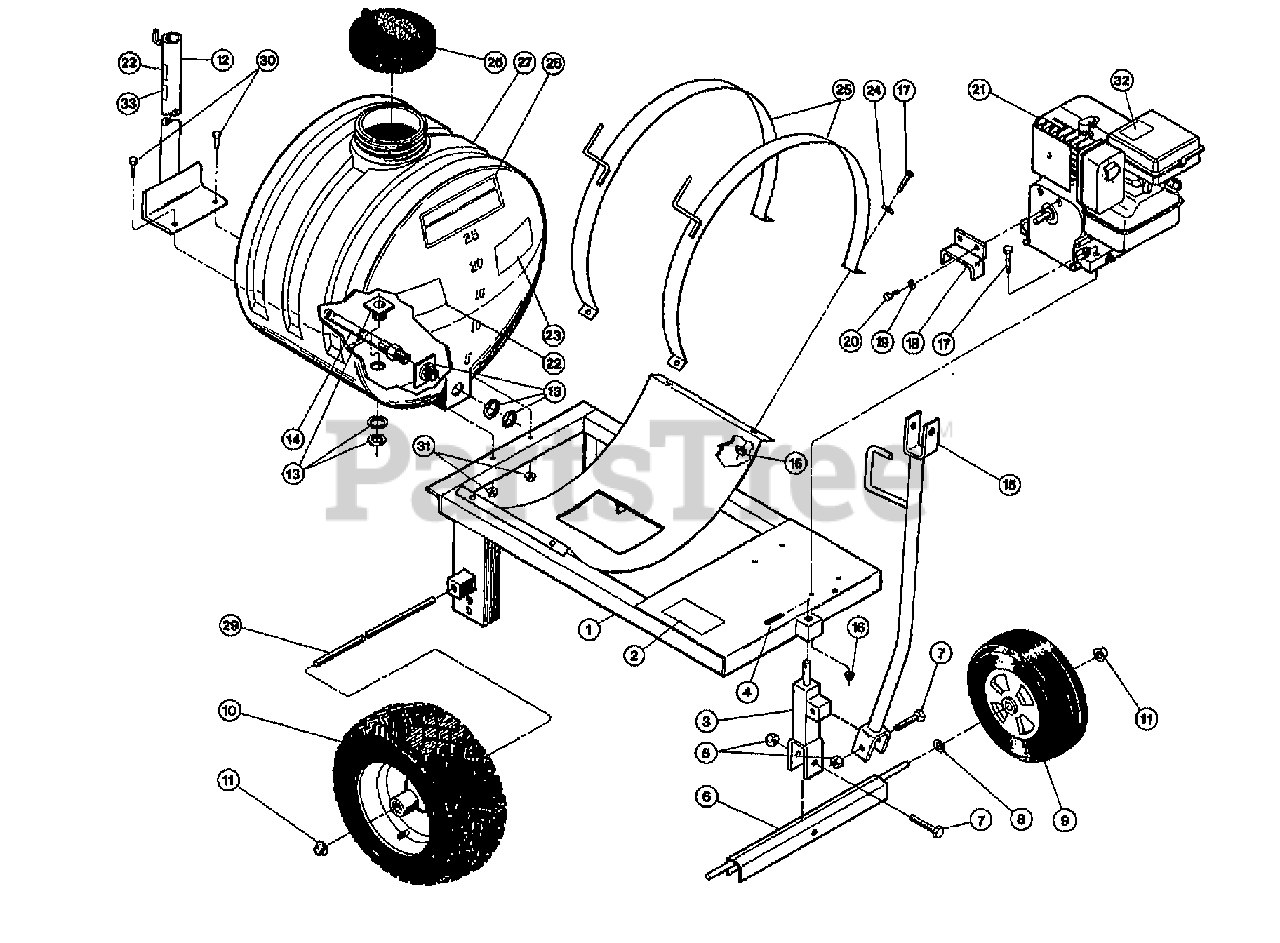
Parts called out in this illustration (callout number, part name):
1	ASSM-UNDERCARRIAGE W21401501
2	DECAL-SAVE
3	ASSM-AXLE PIVOT FRONT
4	PIN-COTTER .120X1.25 ZP
6	ASSM-FRONT AXLE SPRAYER
7	SCR-HH 5/8-11X2.25 G5 ZP
8	WASHER-1.75X.625X.11
9	ASSM-TIRE/WHEEL 11592
10	ASSM-6.5X16 TIRE WPW02202
11	NUT-PUSH 5/8
12	MAST-BOOM*ALIAS*1985814
13	ASSM-BULK HEAD W21254002
14	AGITATOR-JET W33710019
15	HANDLE-TOW BAR
16	NUT-HFLK 5/16-18 ZP
17	SCR-HH 5/16-18X1.5 G5 ZP
18	COVER-DRIVESHAFT SPRAYER
19	WASHER-LK .312 ZP
20	SCR-GRD 5 W02050502FP
22	DECAL-DANGER AVOID W2045146
23	DECAL-ENG SPEED W2045149
24	WASHER-FLAT 5/16 SAE
25	TANK-UP CRDL W/HOSE HGRS
26	CAP-TANK W21254503
27	ASSM-TANK 25 GAL W/DECALS
28	DECAL-LOGO 25 GAL SPRAYER
29	AXLE-REAR W2000109B
30	SCR-HH 5/16-18X1.0 G5 ZP
31	NUT-HFLK 5/16-18 ZP
32	DECAL-HOT SURFACE
33	DECAL-40PSI CAUTION W2045147
